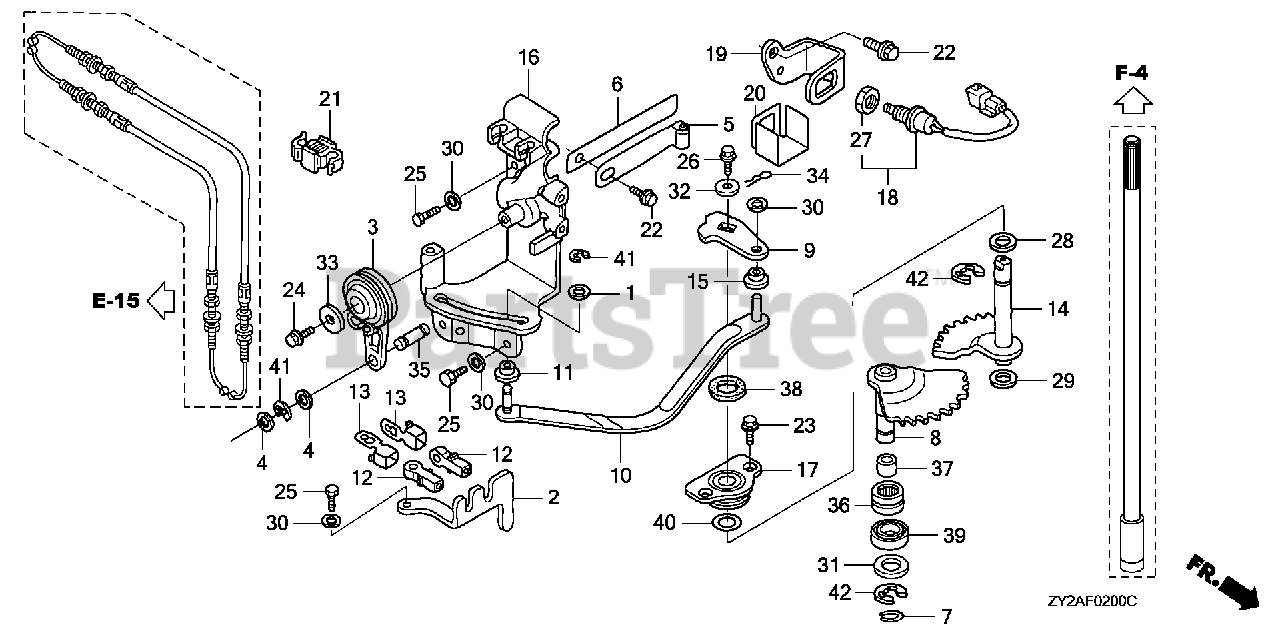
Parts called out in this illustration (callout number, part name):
1	WASHER, AIR CLEANER COVER SETTING
2	PLATE, REMOTE CONTROL CABLE
3	ARM, THROTTLE
4	WASHER, PIVOT
5	SPRING, CLICK
6	SPRING, CLICK ASSIST
7	RING, STOPPER
8	SHAFT, SHIFT (A)
9	ARM, SHIFT
11	COLLAR, SHIFT SLIDER
12	PIVOT, SHIFT
13	PLATE, LOCK
14	SHAFT, SHIFT (B)
15	BUSH, SHIFT ARM
16	BRACKET, SHIFT LINK
17	HOLDER, SEAL
18	SWITCH ASSY., NEUTRAL
19	BRACKET, NEUTRAL SWITCH
20	COVER, NEUTRAL SWITCH
21	CLIP A, WATER VALVE SOLENOID
22	BOLT, FLANGE (6X14) (CT200)
23	BOLT, FLANGE (6X11)
24	BOLT, FLANGE (6X12)
25	BOLT, HEX. (6X16)
26	BOLT, FLANGE (6X16)
27	NUT, HEX. (20MM)
28	WASHER, THRUST (14MM)
29	WASHER, SHIFT SHAFT
30	WASHER, PLAIN (6MM)
32	WASHER, PLAIN (6MM)
33	WASHER, PLAIN (6MM)
34	PIN, SNAP (6MM)
36	BEARING, NEEDLE (20X28X13) (SOLID)
37	RING (INNER) (15X20X13)
38	OIL SEAL (14X26X6)
39	SEAL, WATER (14X26X8)
40	O-RING (26.9X2.4) (NOK)
41	E-RING (4MM)
42	E-RING (12MM)
